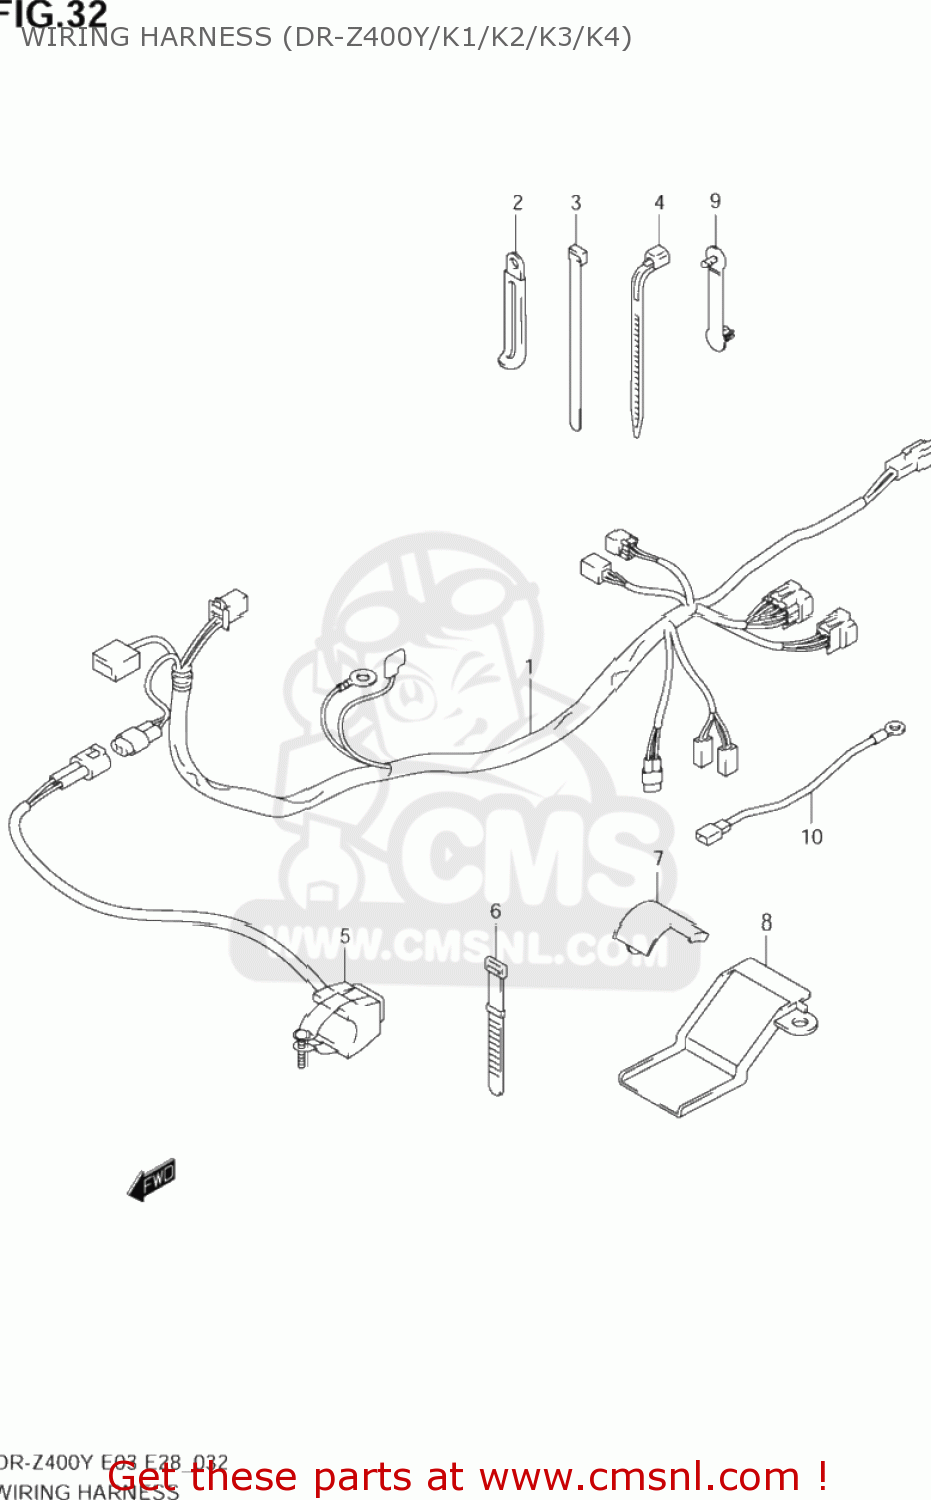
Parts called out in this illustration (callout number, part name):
1	HARNESS,WIRING
2	CLAMP(L:45)
3	CLAMP(L:145)
4	CLAMP(L:125)
5	SWITCH ASSY,ENGINE STOP
6	CLAMP(L:120)
7	PROTECTOR,WIRING HARNESS
8	PROTECTOR,WIRING HARNESS
9	CLAMP(L:63)
10	WIRE,ENGINE EARTH
